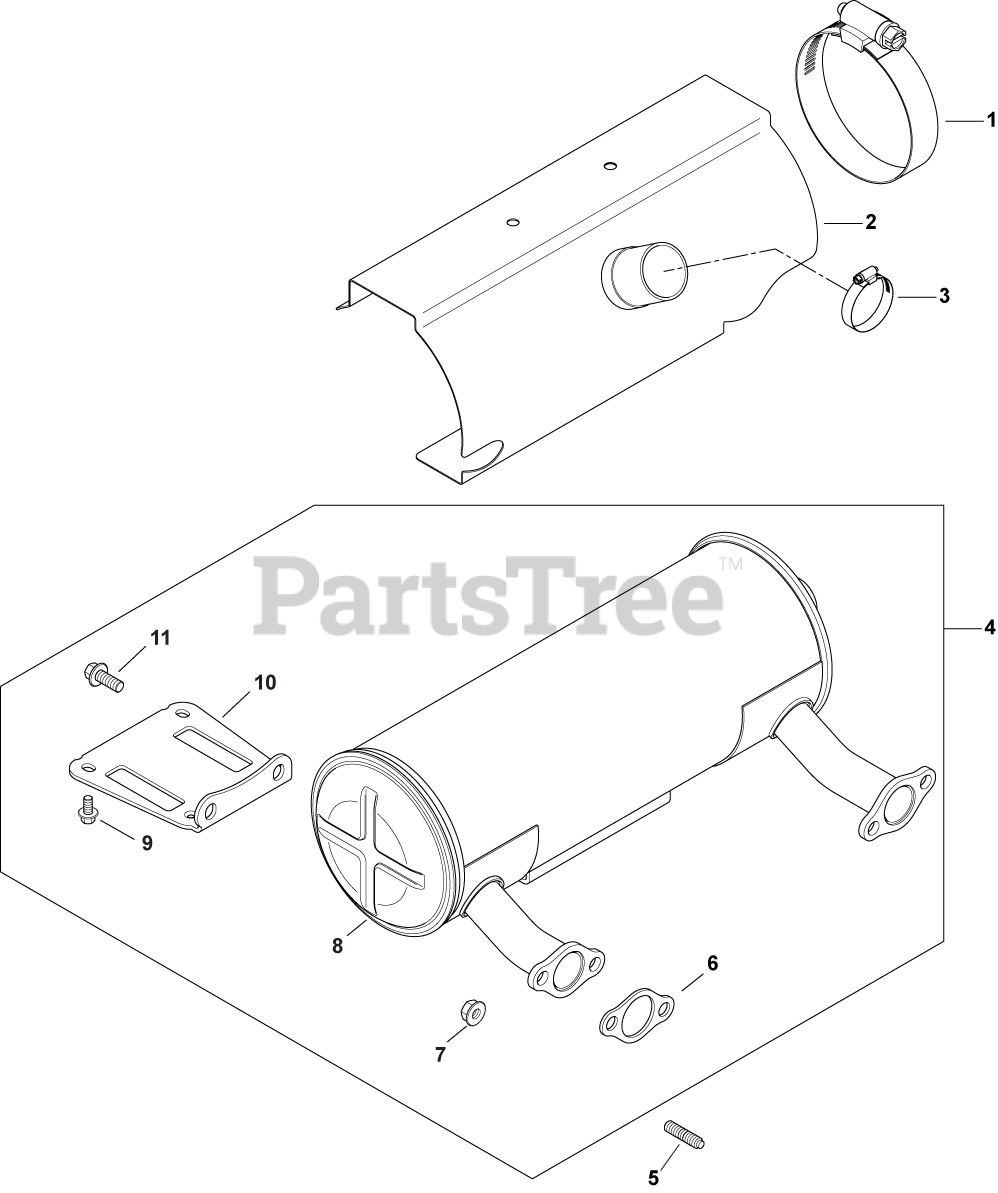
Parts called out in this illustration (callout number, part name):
1	SHIELD, HEAT
2	CLAMP, HOSE
3	CLAMP, HOSE
4	KIT, MUFFLER
5	STUD, EXHAUST-USE 25 072 24-S
6	GASKET, EXHAUST
7	NUT, FLG M8X1.25
8	MUFFLER, CANISTER-STRT OUTLET - USE 24 068 129-S
9	SCREW, FLG M6X1.0X12
10	BRACKET, MUFFLER
11	SCREW, FLG M8X1.25X20
